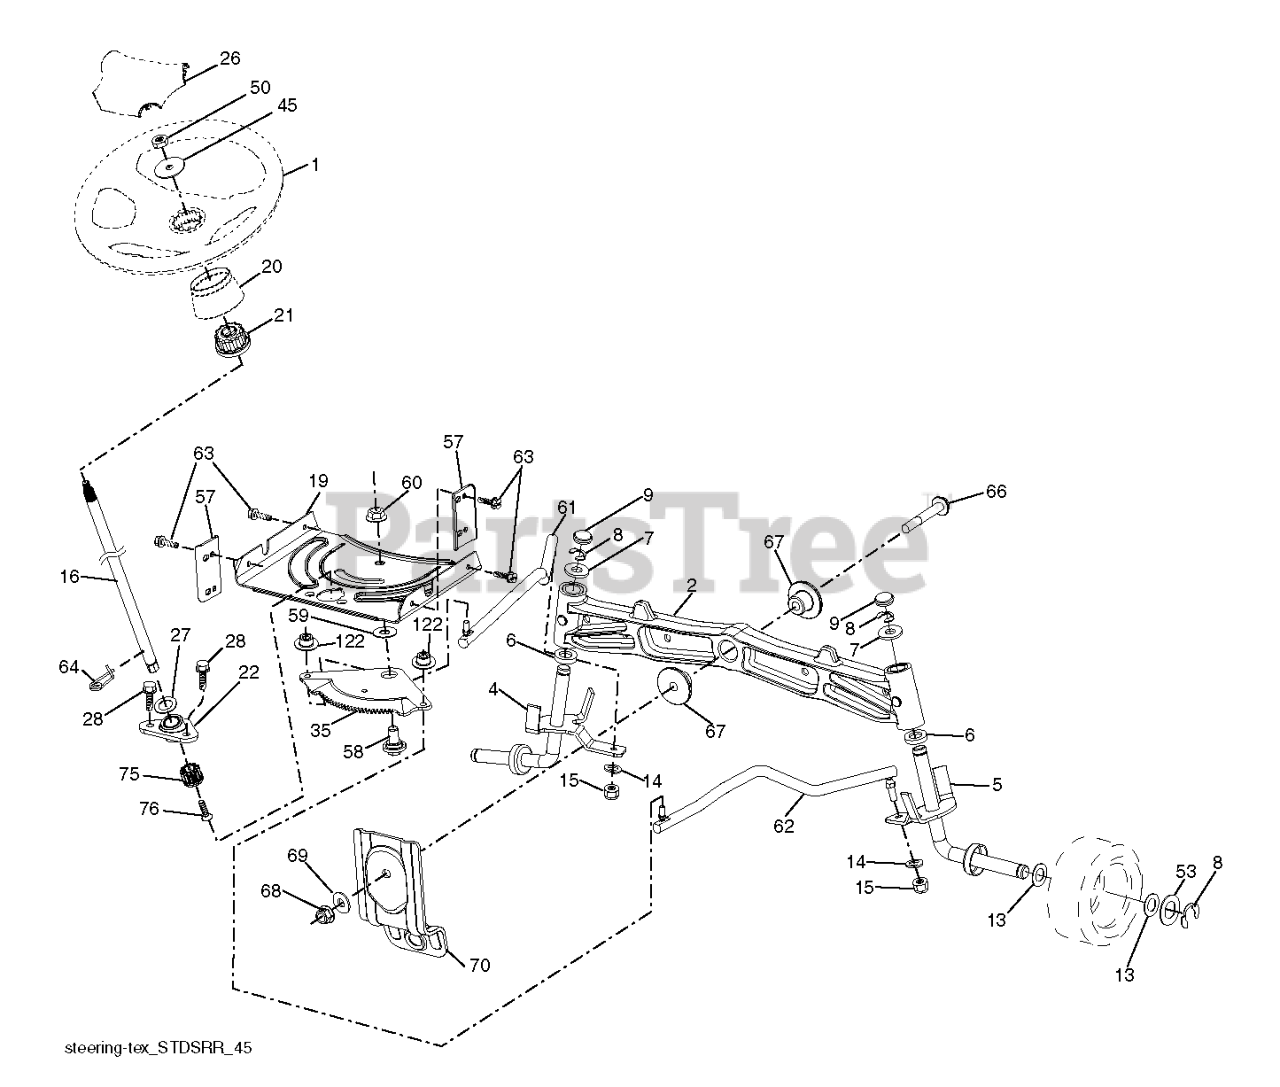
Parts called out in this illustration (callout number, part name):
1	WHEEL.STEERING.MLT.BR.YEL/OVRM
2	AXLE.CAST.IRON
4	SPINDLE.WELDED.LH.15"TEX
5	SPINDLE.WELDED.RH.15"T
6	Bearing Race Thrust Harden (AYP part number)
7	Washer 25/32 x 1-5/8 x 16 Gauge (AYP part number)
8	Ring, Klip #T5304-75 (AYP part number)
9	Cap Spindle Fr Top Blk (AYP part number)
13	Washer 25/32 x 1-1/4 x 16 Gauge (AYP part number)
14	SLW 3/8 STD
15	Nut, Crownlock 3/8-24 (AYP part number)
16	SHAFT.STEER.2HIGH.SPLND.PLATED
19	PLATE.STEER.DDL.NLT/NG
20	BOOT.STRNG.PREDATOR.YT/GT.428
21	ADAPTER.WHEEL.STEER.SPLND.ALUM
22	BEARING.SHAFT.STEER.LOWER.625
26	CAP.WHL.STRNG.MULTI.BRND.YEL
27	Washer 21/32 x 1 x 16 Gauge (AYP part number)
28	SCREW, 3/8-16X3/4
35	GEAR.SECTOR.PLATE.DDL.
45	WASHER.3/8ID.2-3/8OD.12GA.PLTD
50	NUT LOCK FLG 3/8-16 UNC
53	WASHER.HARDENED
57	BRACKET.UPSTOP.TEX
58	BOLT.SHOULDER.SECTOR.P
59	WASHER.THURST.SECTOR.S
60	NUT FLANGE LOCK 5/8-11
61	DRAGLINK.LH.BALLSTUD.D
62	DRAGLINK.RH.BALLSTUD.D
63	SCREW
64	RETAINER.CLIP.SPRING.S
66	BOLT HEX FGHD 7/16-14 X 3 SERR
67	BUSHING.PM.FRONT AXLE
68	NUT.LOCK.FLANGE.7/16
69	WASHER.1.5X.505X.118
70	BRACKET.FRT.DECK.SUSP.RR.MT431
75	PINION.ZINC PLATED
76	SCREW HEAD SOCKET LRVB
122	CAP.GEAR.SECTOR.TEX
